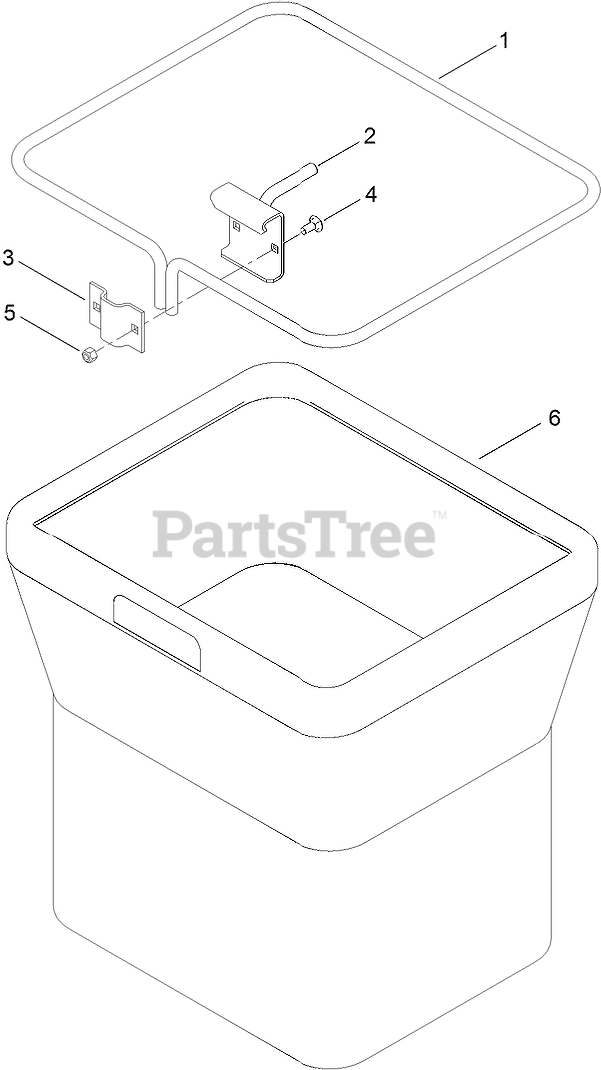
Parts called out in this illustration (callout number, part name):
1	FRAME-BAG
2	HANGER ASM
4	BOLT-CARR
5	NUT-LOCK, NI
